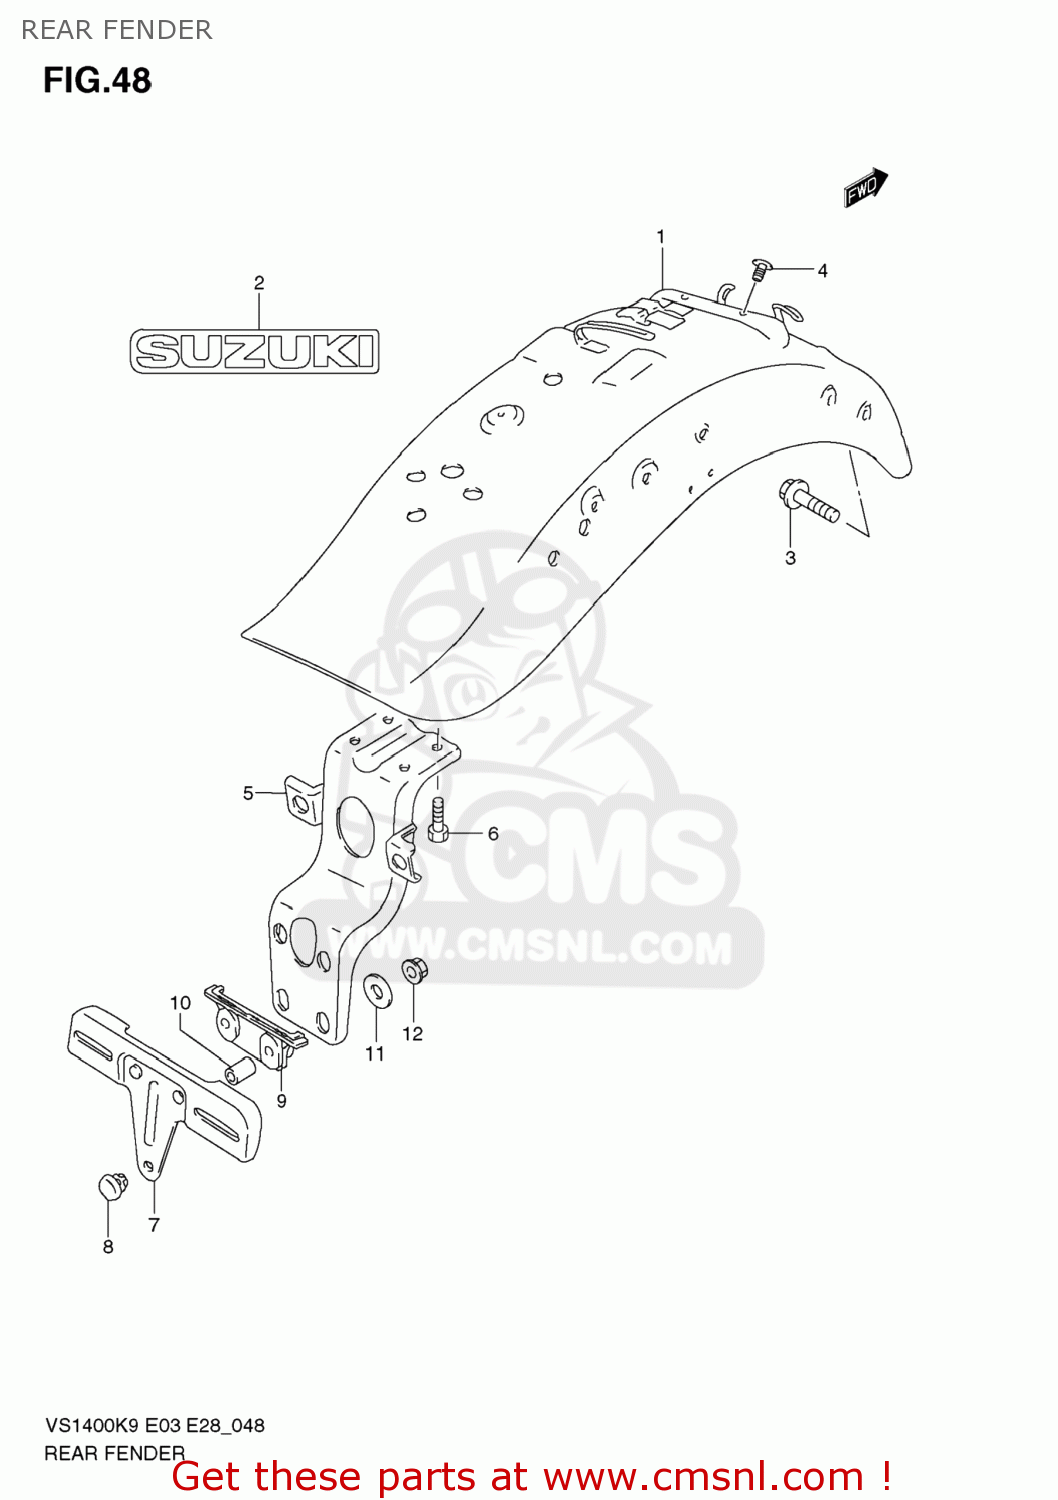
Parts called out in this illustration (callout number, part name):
1	FENDER ASSY,RR
2	EMBLEM,SUZUKI
3	BOLT
4	CAP(OD:12)
5	BRACKET,RR COMBINATION LAMP
6	BOLT
7	PLATE,RR LICENSE
8	CUSHION
9	CUSHION,RR LICENSE PLATE
10	SPACER(5.5X8X14.3)
11	WASHER(5.5X20X1.2)
12	NUT
